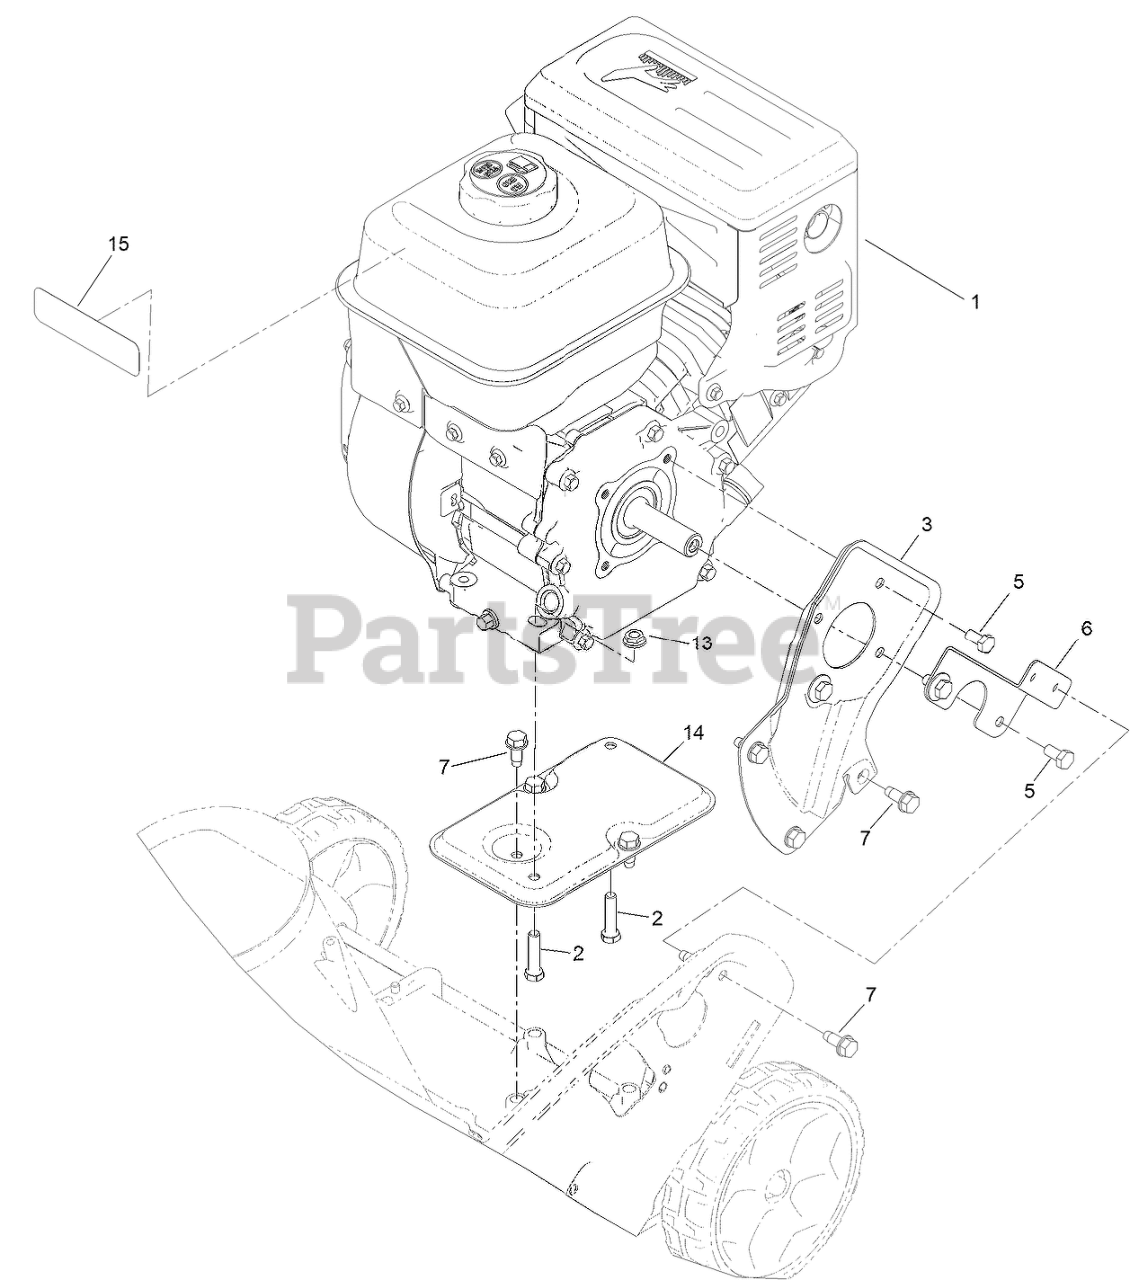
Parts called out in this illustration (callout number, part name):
1	ENGINE - G250FS-4
2	SCREW-HH
3	PLATE-ENGINE, PTO
5	BOLT
6	SUPPORT-ENGINE, SIDE
7	SCREW-THD ROLL, HWH
13	NUT-HF
14	SUPPORT-ENGINE
15	DECAL-ENGINE COMMERCIAL
